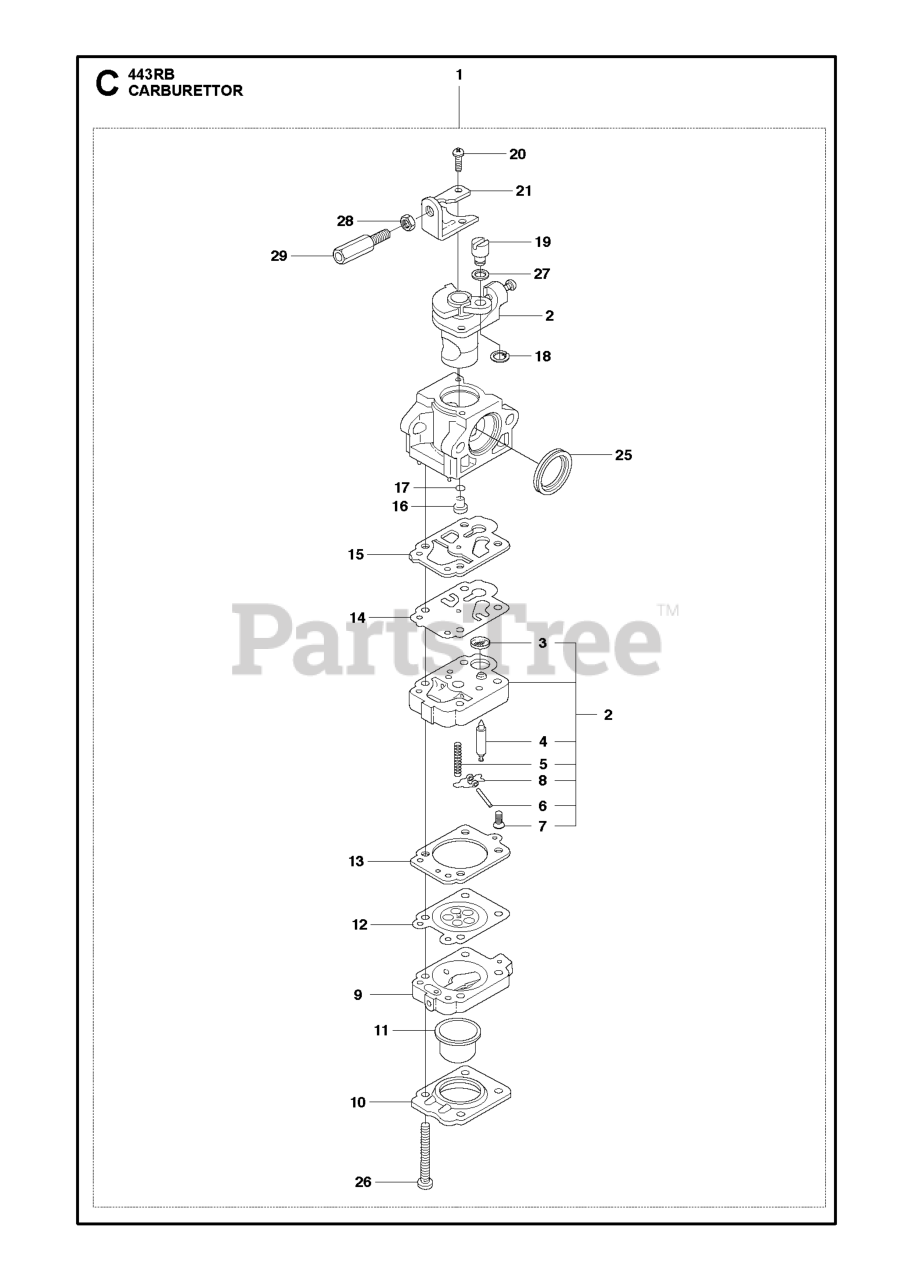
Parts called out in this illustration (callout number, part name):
2	CARBURETOR BODY
3	SCREEN
4	VALVE INLET
15	GASKET
25	RING PACKING
28	NUT
